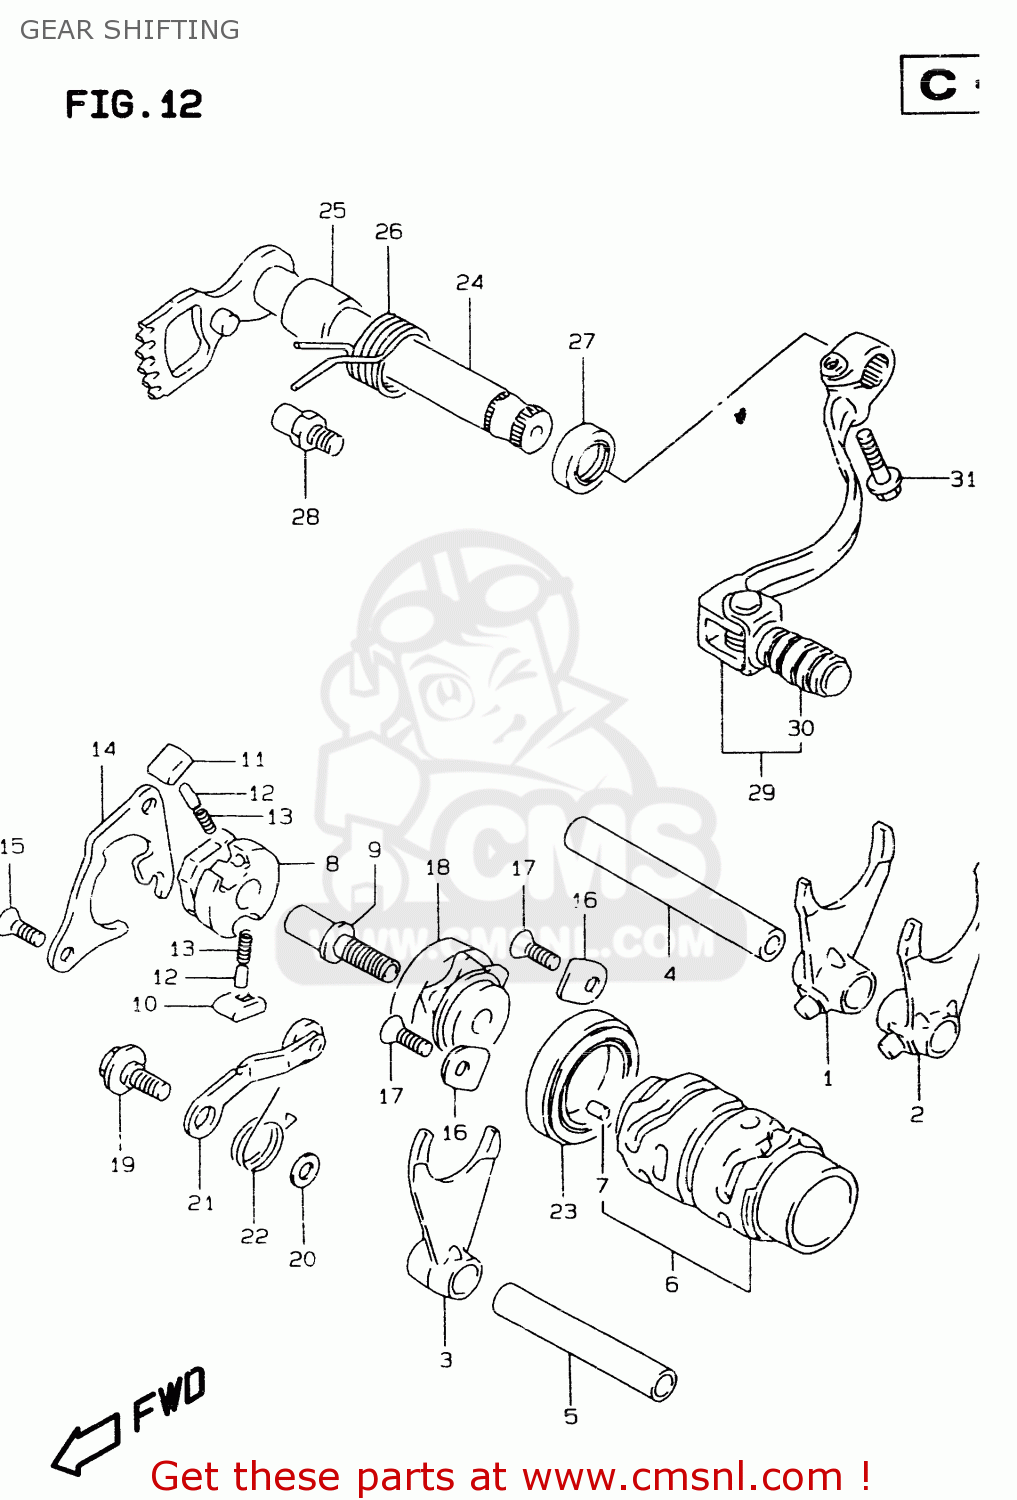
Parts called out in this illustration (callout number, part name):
1	FORK,GEAR SHIFT NO.1
2	FORK,GEAR SHIFT NO.2
3	FORK,GEAR SHIFT NO.3
4	SHAFT,GEAR SHIFT FORK
5	SHAFT,GEAR SHIFT FORK
6	CAM,GEAR SHIFT
7	PIN
8	GEAR,GEARSHIFT CAM DRIVE
9	PIN,SHIFT CAM DRIVEN GEAR
10	PAWL,GEAR SHIFT NO.1
11	PAWL,GEAR SHIFT NO.2
12	PIN(5X8)
13	SPRING
14	LIFTER,GEAR SHIFT POLE
15	SCREW
16	RETAINER,COUNTER BEARING,R
17	SCREW
18	PLATE,SHIFT CAM STOPPER
19	BOLT(6X14.3)
20	WASHER
21	STOPPER,SHIFT CAM
22	SPRING
23	BEARING
24	SHAFT,GEAR SHIFT
25	SPACER(14X20X17.5)
26	SPRING
27	SEAL,OIL(14X22X6)
28	STOPPER,GEAR SHIFT CAM
29	LEVER ASSEMBLY,GEAR SHIFTING
30	RUBBER,GEAR SHIFT PEDAL
31	BOLT,G/S SWITC
